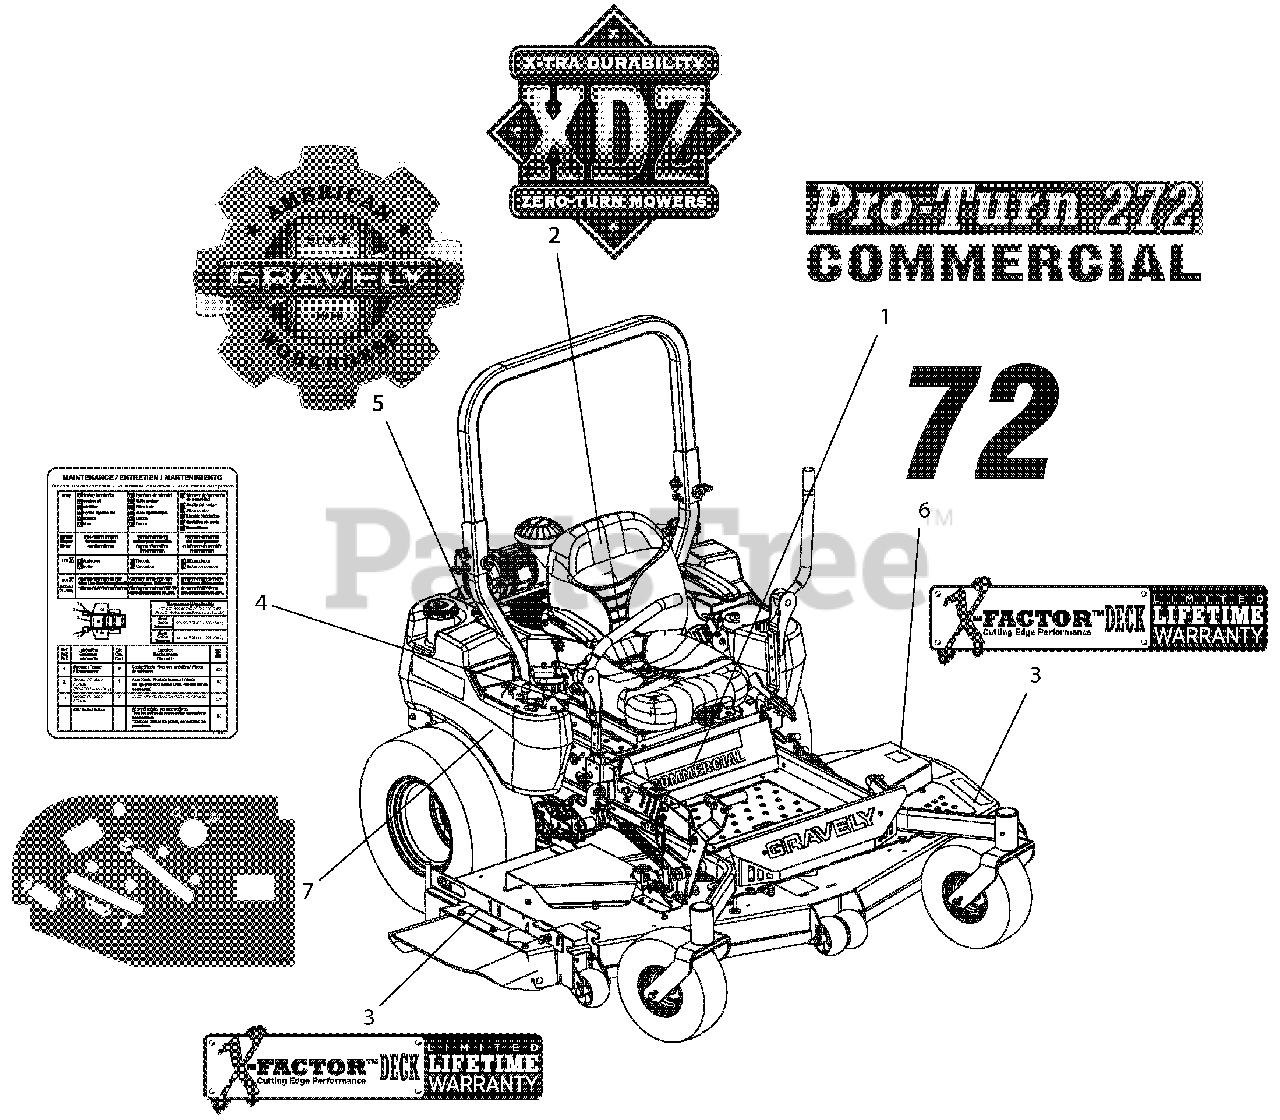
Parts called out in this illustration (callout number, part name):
1	DECAL, PRO-TURN 272
2	DECAL, XDZ
3	DECAL, X-FACTOR DECK
4	DECAL, MAINTENANCE
5	DECAL, GRAVELY HERITAGE-LARGE
6	DECAL, 72"
7	DECAL, CONTROL PANEL
